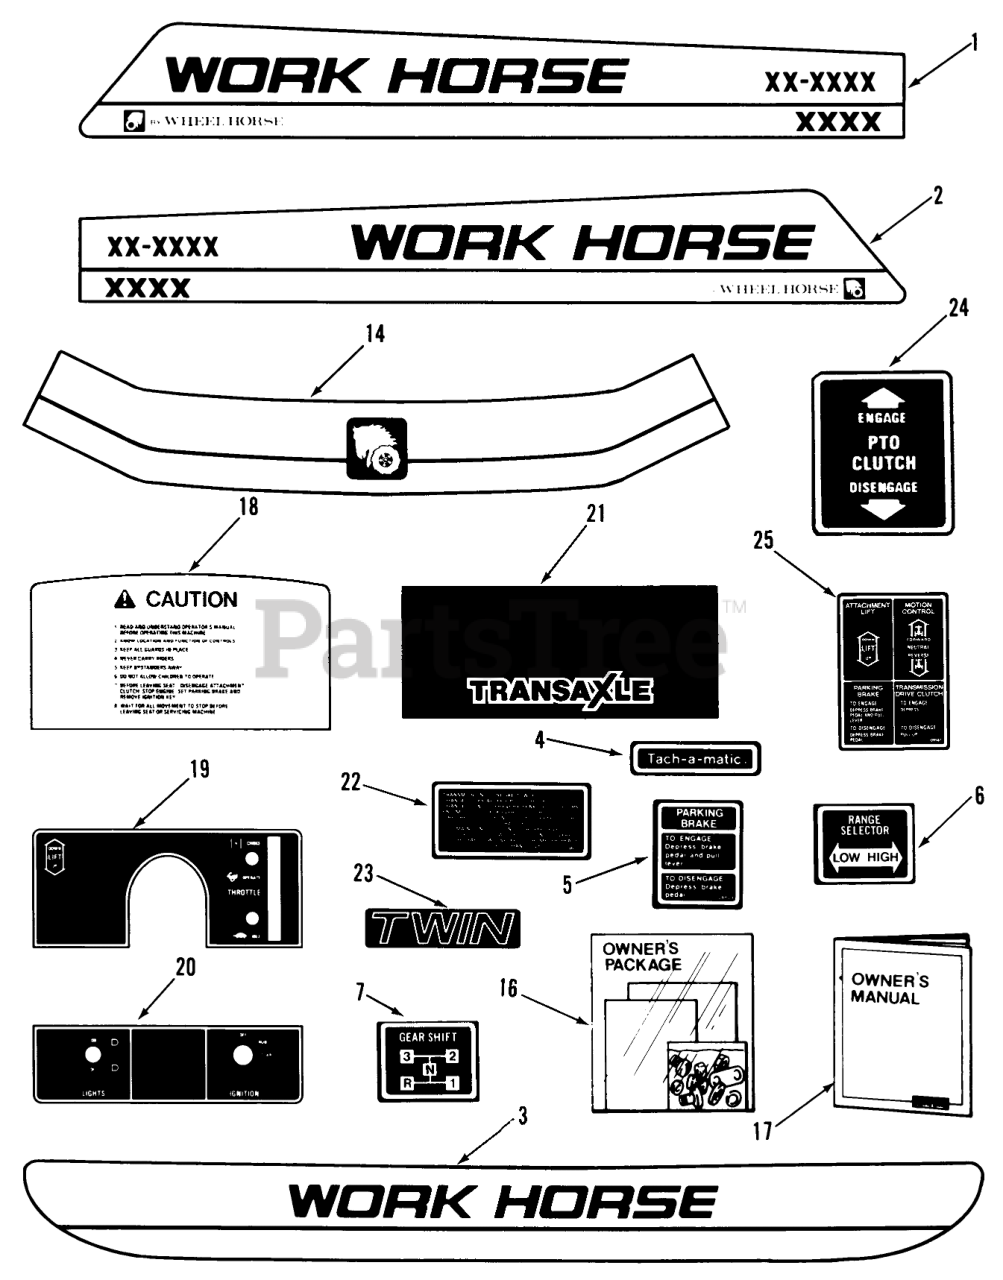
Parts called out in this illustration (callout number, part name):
1	Decal LH GT-1100 8-Speed
1	HOOD DECAL LH
2	HOOD DECAL RH
3	Decal Rear
4	DECAL-TACHAMATIC
5	DECAL-PARKING BRAKE
6	DECAL HI-LO
7	DECAL-SHIFT
14	DECAL - HOOD FRONT
16	Loose Parts Package GT-1100 Only
16	Loose Parts Package GT-1600, GT-1800 Only
17	Owner-s Manual-Tractor
18	DECAL - CAUTION
19	DECAL - LOWER DASH
19	Decal-Dash GT-1800 Only
20	DECAL-BACK PLATE-SWI
21	DECAL - TRANSAXLE
22	Decal-Maintenance
23	Decal-Engine LT-1600 Only
24	DECAL-PTO CLUTCH
25	Decal-Speed Control, Lift, Parking Brake GT-1800 Only
